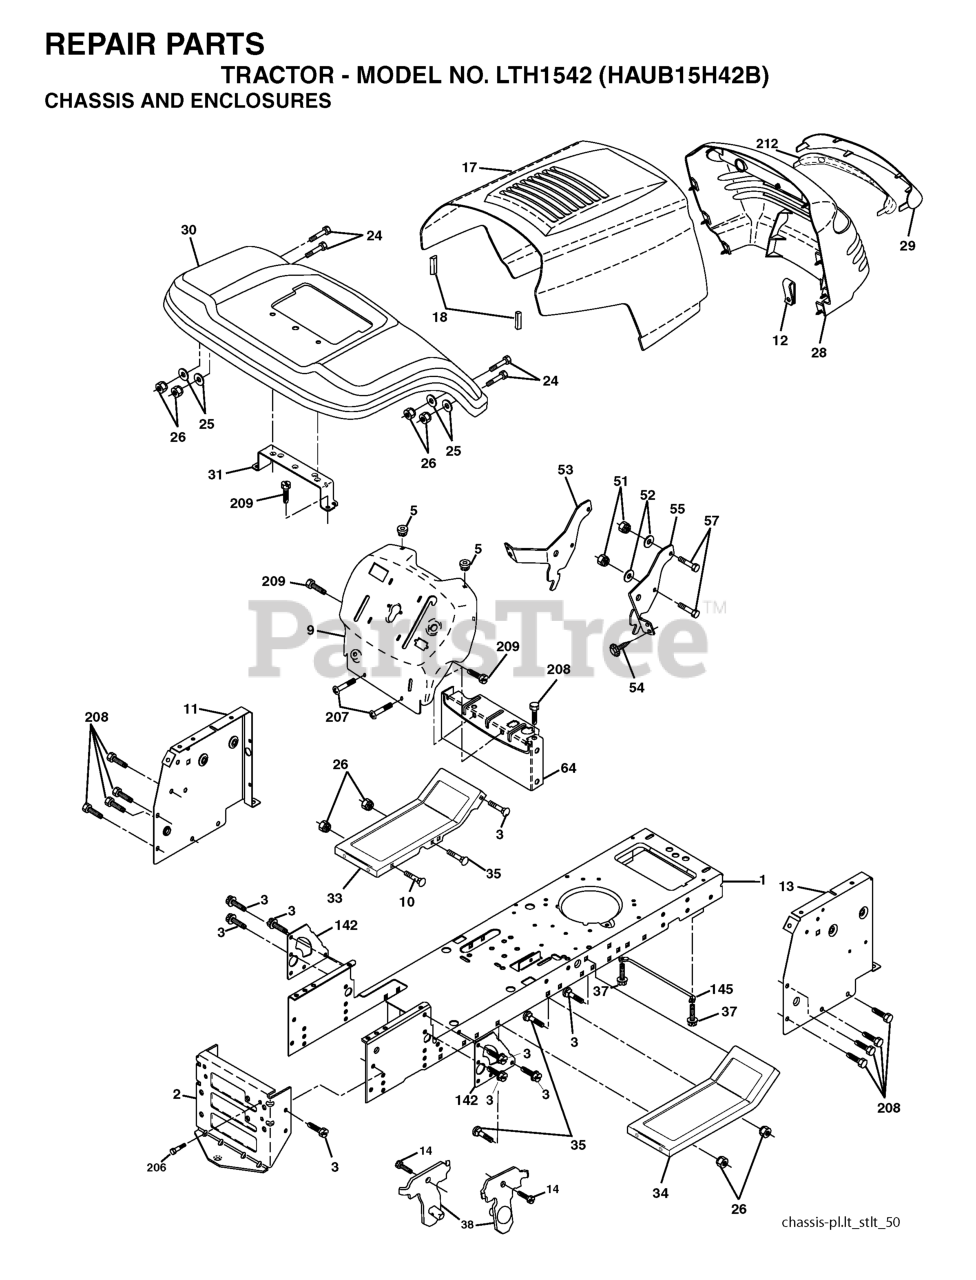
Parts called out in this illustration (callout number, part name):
1	CHASSIS STAMPING
2	DRAWBAR, 12GA
3	SCREW 3/8-16X3/4
5	BUMPER.RUBBER.HOOD
9	DASH
10	BOLT D
11	PANEL.DASH.LH.LTX
13	PANEL DASH RH
17	HOOD ASM.
18	BUMPER.HOOD.LARGE.1.75"
25	WASHER
26	NUT
28	GRILL ASSEMBLY
29	LENS P/L
30	FENDER
31	BRACKET FENDER
33	FOOTREST PNT LH
34	FOOTREST PNT RH
37	Screw 5/16-18 x 1/2 Hex, Self Tapping 5/16-18 x 1/2
38	BRACKET.ASM.PIVOT.MOWER.REAR
51	LOCKNUT.NYLOC.1/4-20
53	BRACKET.GRILLE.LH
54	SCREW.HEX.WS.HD.8-18 X 7/8
57	BOLT
58	AIR DUCT P/L/LT
64	DASH LOWER
142	PLATE REINFORCEMENT
145	ROD PIVOT CHASSIS/HOOD
206	SHOULDER BOLT 5/16-18TT
207	SCREW, 5/16-18 X 1/2
208	SCREW 3/8-16X1/2
209	SCREW, 3/8-16X3/4
212	REPL BY 532 1745-03
